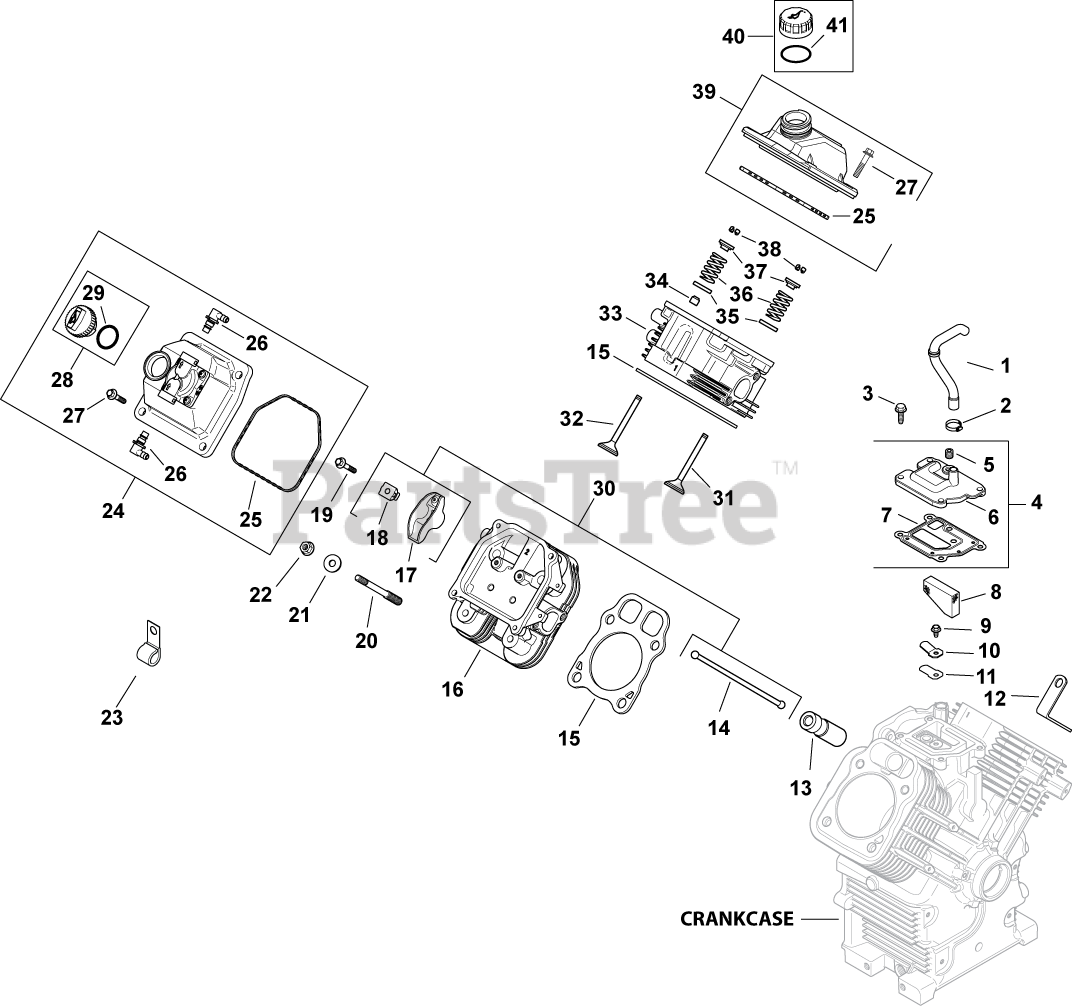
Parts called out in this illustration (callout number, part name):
1	HOSE, BREATHER
2	CLAMP, HOSE (KM)-USE 25 237 31-S
3	SCREW,FLG THD FRM M6X1.0X20-(#25086396S)
4	KIT, BREATHER ASSEMBLY
5	PLUG, CTSK PIPE 1/8"
6	COVER, BREATHER -USE 24 033 01-S
7	GASKET, BREATHER-USE 24 041 67-S
8	FILTER, BREATHER
9	SCREW, FLG THD FRM M5X.8X10
10	RETAINER, REED
11	REED, BREATHER
12	STRAP, LIFTING-USE 25 445 03-S
13	LIFTER, HYDRAULIC VALVE-USE 25 351 10-S
14	ROD, PUSH
15	CYL HEAD GASKET KIT-USE 24 841 04-S
16	KIT, CYLINDER HEAD #2 USE 24 318 149-S
17	ARM, ROCKER
18	PIVOT, ROCKER ARM
19	SCREW, FLG M6X1.0X34
20	STUD, M8X1.25
21	WASHER, FLAT 8.6 MM
22	NUT, FLG M8X1.25
23	CLIP, CABLE
24	KIT, VALVE COVER-FUEL PUMP
25	O-RING (YELLOW), VALVE COVER
26	KIT, 90 DEG. FITTING
27	SCREW, FLG M6X1.0X30
28	CAP ASSY, OIL FILL (YELLOW)
29	O-RING-USE 24 153 32-S
30	KIT, VALVE TRAIN
31	VALVE, INTAKE (STD)
32	VALVE, EXHAUST (STD) - USE 32 016 01-S
33	KIT, CYLINDER HEAD #1 - (#24318143S)
34	SEAL, VALVE STEM - (#2503214S)
35	RETAINER, SPRING
36	SPRING, VALVE
37	RETAINER, VALVE SPRING - USE 25 173 28-S
38	KIT, RETAINER
39	KIT, VALVE COVER-OIL FILL
40	KIT, OIL FILL CAP (YELLOW)
41	O-RING, DIPSTICK
2401602-S	VALVE, EXHAUST (.25)
2401702-S	VALVE, INTAKE (.25)
24755147-S	KIT, CYLINDER HEAD HARDWARE
